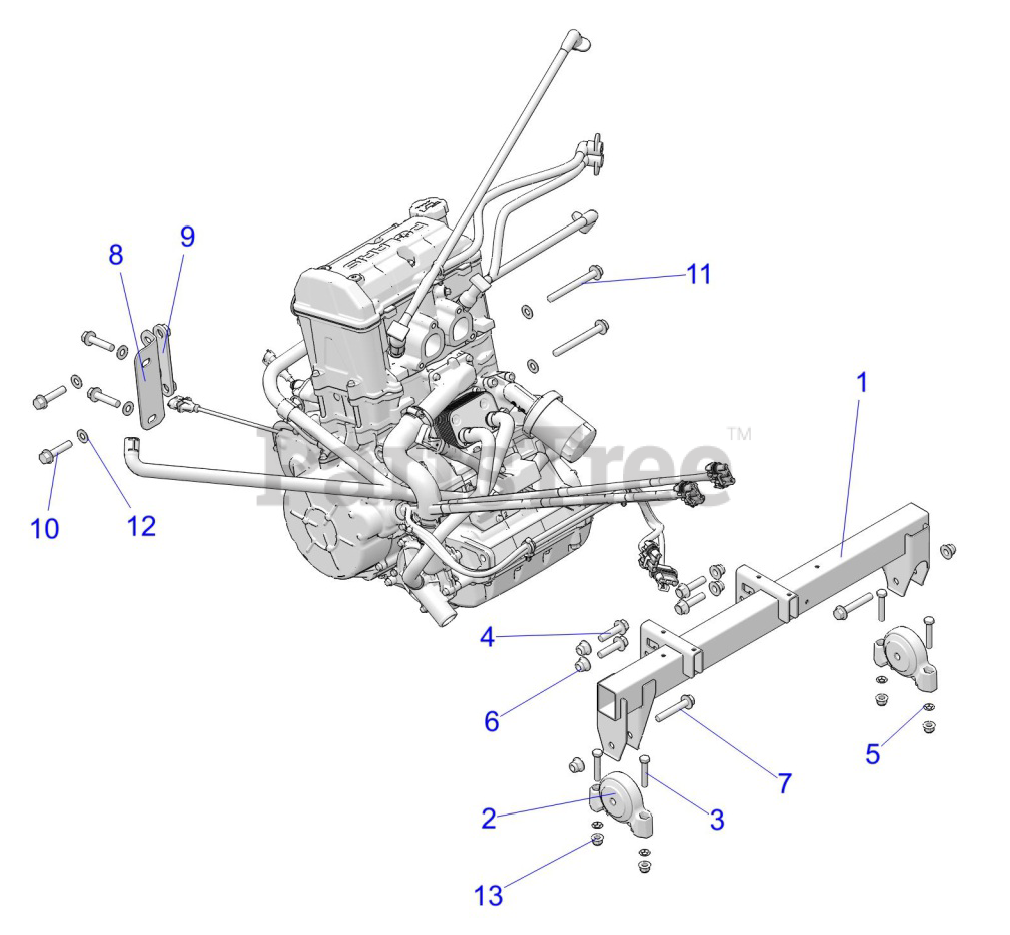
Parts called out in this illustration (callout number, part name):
1	WELD-MOUNT-ENGINE-BLK
2	MOUNT-ISOLATOR-DRIVELINE
3	SCR-HH M8X1.25X45 8.8 ZOD
4	SCR-HXFL-M10X1.25X40 8.8 ZOD
6	NUT-M10X1.25-FLG-NYLOC-OLIVE D
7	BOLT-M10X1.25X60-HXFLG-OLIVE D
8	BRKT-COUPLER- TRANS
9	WELD-NUT-PLATE
10	SCR-HXFL-M10X1.25X45 8.8 ZOD
11	SCR-HXFL-M10X1.25X95 10.9 ZOD
12	WASHER-3/8 FW
13	NUT-M8X1.25-FLG-NYLOC-OLIVE D
